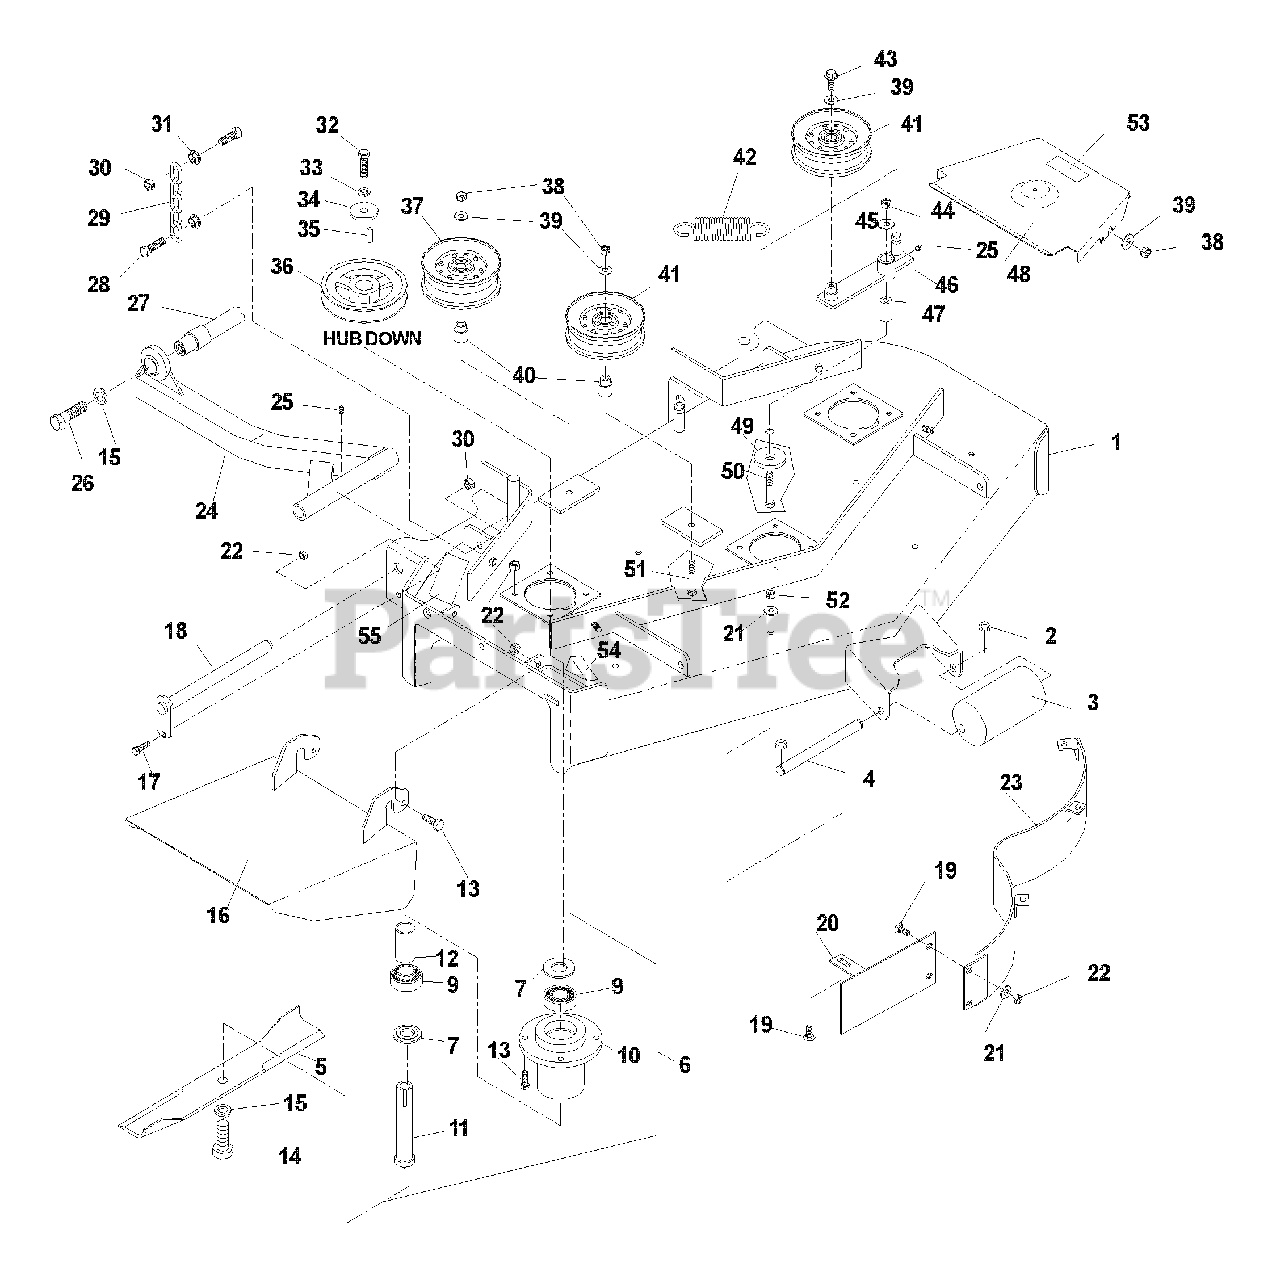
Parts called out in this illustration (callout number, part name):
1	DECK W/DECALS
2	1/2" E-RING
3	ROLLER, LONG
4	AXLE, ROLLER
5	BLADE 14 7/8"
6	CUTTER HOUSING, COMPLETE
7	COMBO, SPACER
9	BEARING
13	HCS 5/16C X 1 1/4
14	HCS 5/8F X 1 1/4
15	LOCKWASHER
16	DISCHARGE CHUTE
17	HCS 5/16C X 3/4
19	CARRIAGE BOLT 5/16 X 5/8
20	CENTER BAFFLE
21	WASHER 5/16C, NYLOC
22	NUT 5/16 CTR. LOCK
23	MAIN BAFFLE
24	STRUT - RIGHT
24	STRUT - LEFT
25	1/4-28 ZERK
26	HCS 5/16C X 2
27	STRUT MT. WLD.
28	HCS 7/16C X 1 1/2
30	7/16C CTR. LOCK
31	7/16C WHIZ NUT
32	HCS 7/16F X 1 1/2
33	7/16 LOCKWASHER
35	KEY 1/4 SQ. X 1 1/8
37	IDLER PULLEY 1.62
38	NUT 3/8C, NYLOC
39	WASHER 3/8 STD.
40	IDLER BUSHING
41	IDLER PULLEY 1.31
43	HCS 3/8C X 1
44	NUT 1/2C NYLOC
45	WASHER 1/2 STD.
47	PIVOT BUSHING
48	BELT SHIELD
49	SUPPORT WASHER
50	HCS 1/2C X 3 1/4
51	HCS 3/8C X 2 3/4
53	DECAL, NO STEP
54	DECAL, CPSC
55	DECAL, DANGER
